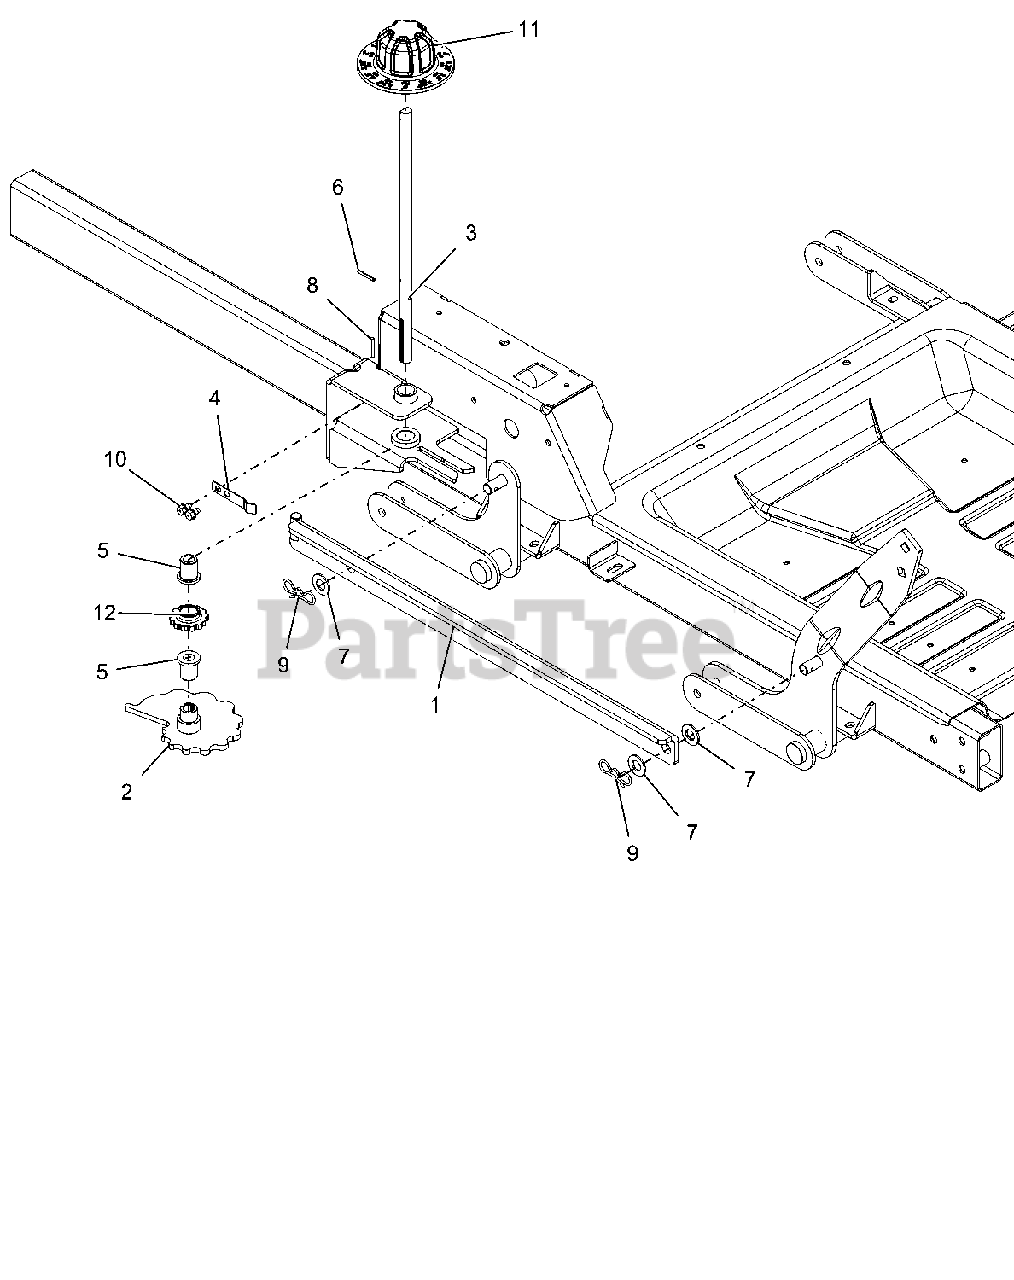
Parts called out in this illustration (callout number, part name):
1	WLDMT, HOC LINK-BLACK
2	WLDMT, HOC CAM
3	CAMSHAFT, HOC
4	ARM, HOC DETENT
5	BUSHING, FLANGE .503X.75X.875X1.0
6	PIN-ROLL .125X1.00
7	WSHR-FL-NYL .518X1.00X.08
8	KEY, 1/8 X 1/8 X 1.0 REV
9	PIN, BOWTIE LOCKING .091X1.875
10	SCR-TAP .25-20X.37 HWH YWZ TR
11	KNOB, HOC
12	CAM, HOC INDEX
